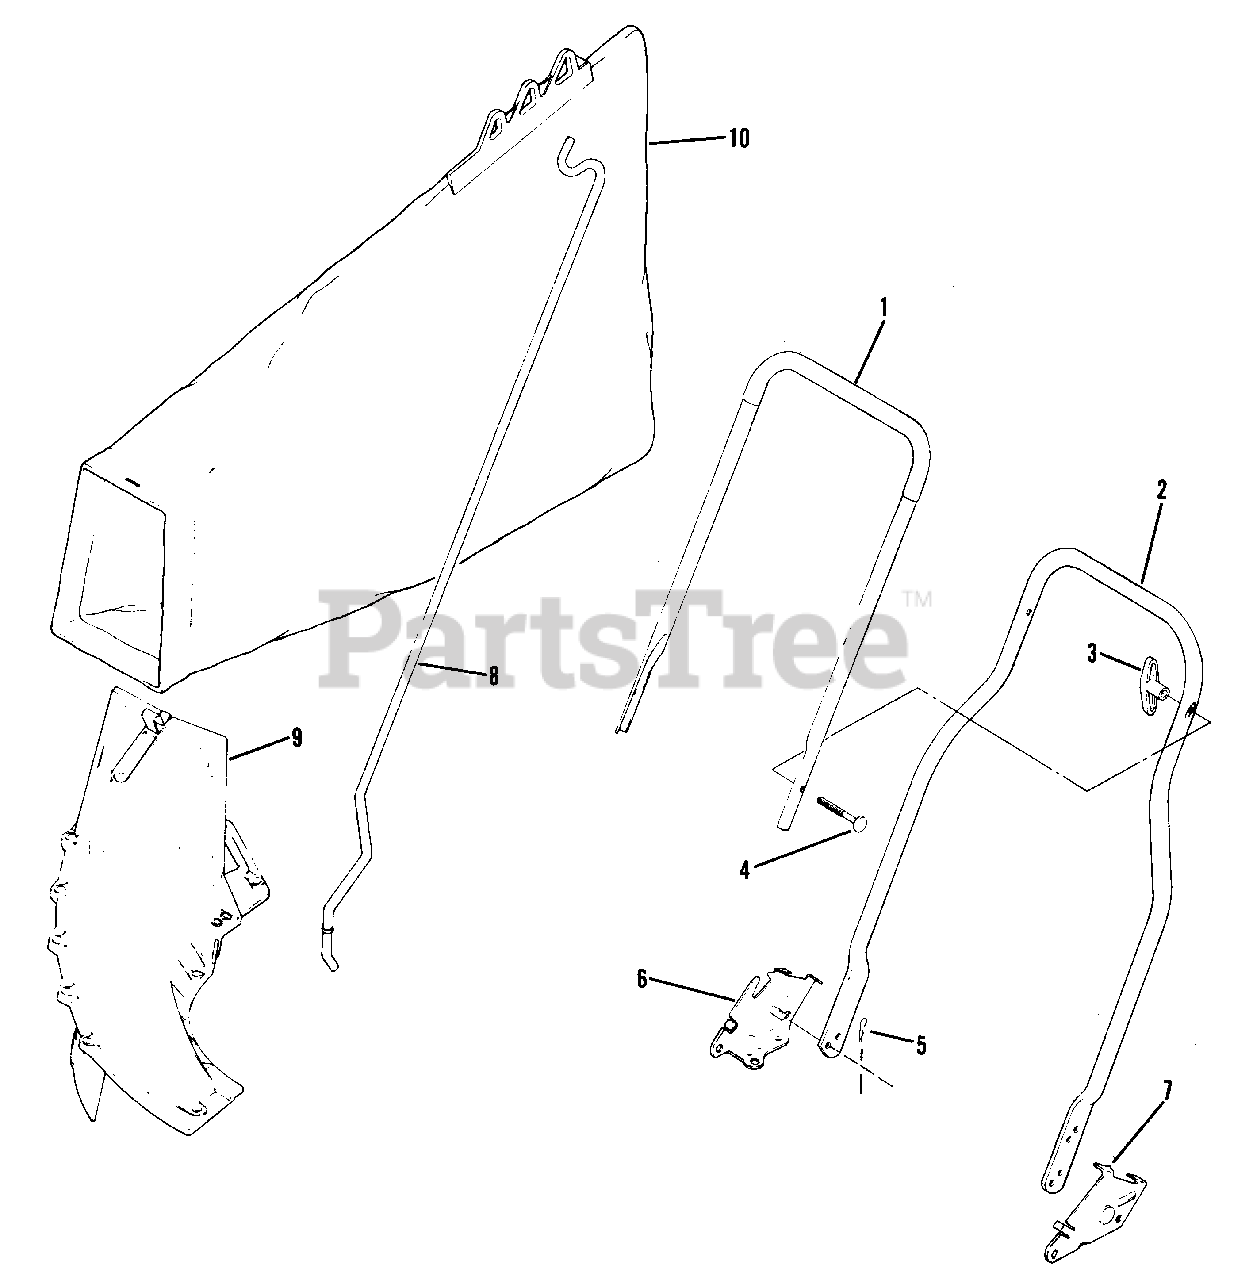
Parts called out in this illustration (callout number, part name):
1	Top Handle & Grip Assembly
2	Handle Section-Bottom
3	Knob
4	Screw
5	Hair Pin
6	Handle Bracket-R.H.
7	Handle Bracket-L.H.
8	Rod-Grass Bag
9	Chute Assembly
10	Bag Assembly
